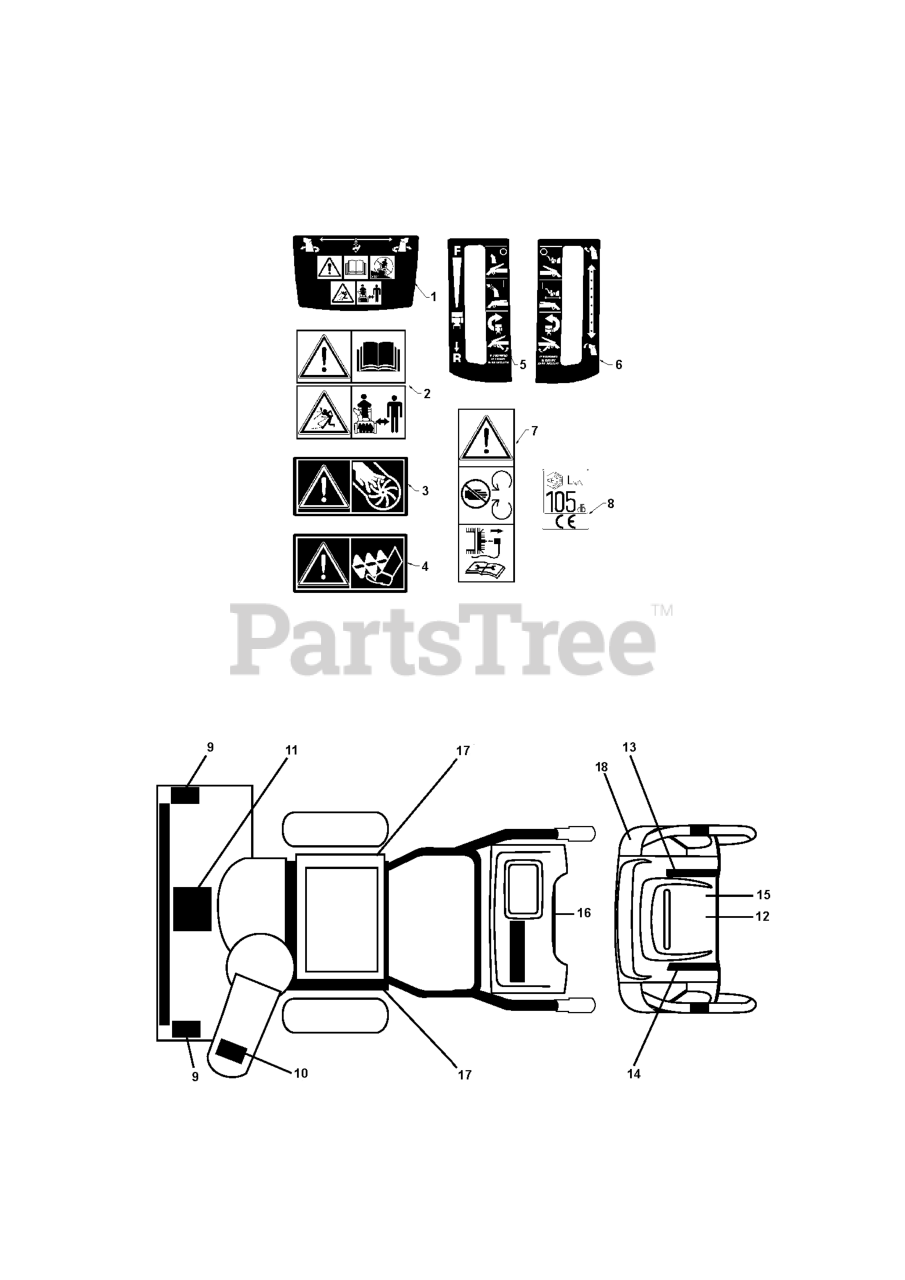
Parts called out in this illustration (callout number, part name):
2	DECAL.AUGER."
3	DECAL.CHUTE.SAFETY.
3	DECAL.CHUTE.SAFETY.EU/SC.17
4	DECAL.AUGER.SAFETY.
5	DECAL CONSOLE DECAL DECAL.SNOW
6	DECAL CONSOLE DECAL DECAL.SNOW
7	DECAL.BELT.GUARD.
8	DECAL.NOISE.LEVEL.105DB/CE.EAC
8	DECAL.NOISE.LEV.105/CE.EAC.UKR
8	DECAL.FENDER
9	DECAL.AUGER.SAFETY.
10	DECAL.CHUTE.SAFETY.EU/SC.17
10	DECAL.CHUTE.SAFETY.
11	DECAL.AUGER."
13	DECAL CONSOLE DECAL DECAL.SNOW
14	DECAL CONSOLE DECAL DECAL.SNOW
15	DECAL.CONSOLE.HAND.WARMER
16	DECAL.NOISE.LEVEL.105DB/CE.EAC
16	DECAL.NOISE.LEV.105/CE.EAC.UKR
16	DECAL.FENDER
17	DECAL.BELT.GUARD.
18	DECAL.CONSOLE.HAND.WARMER
